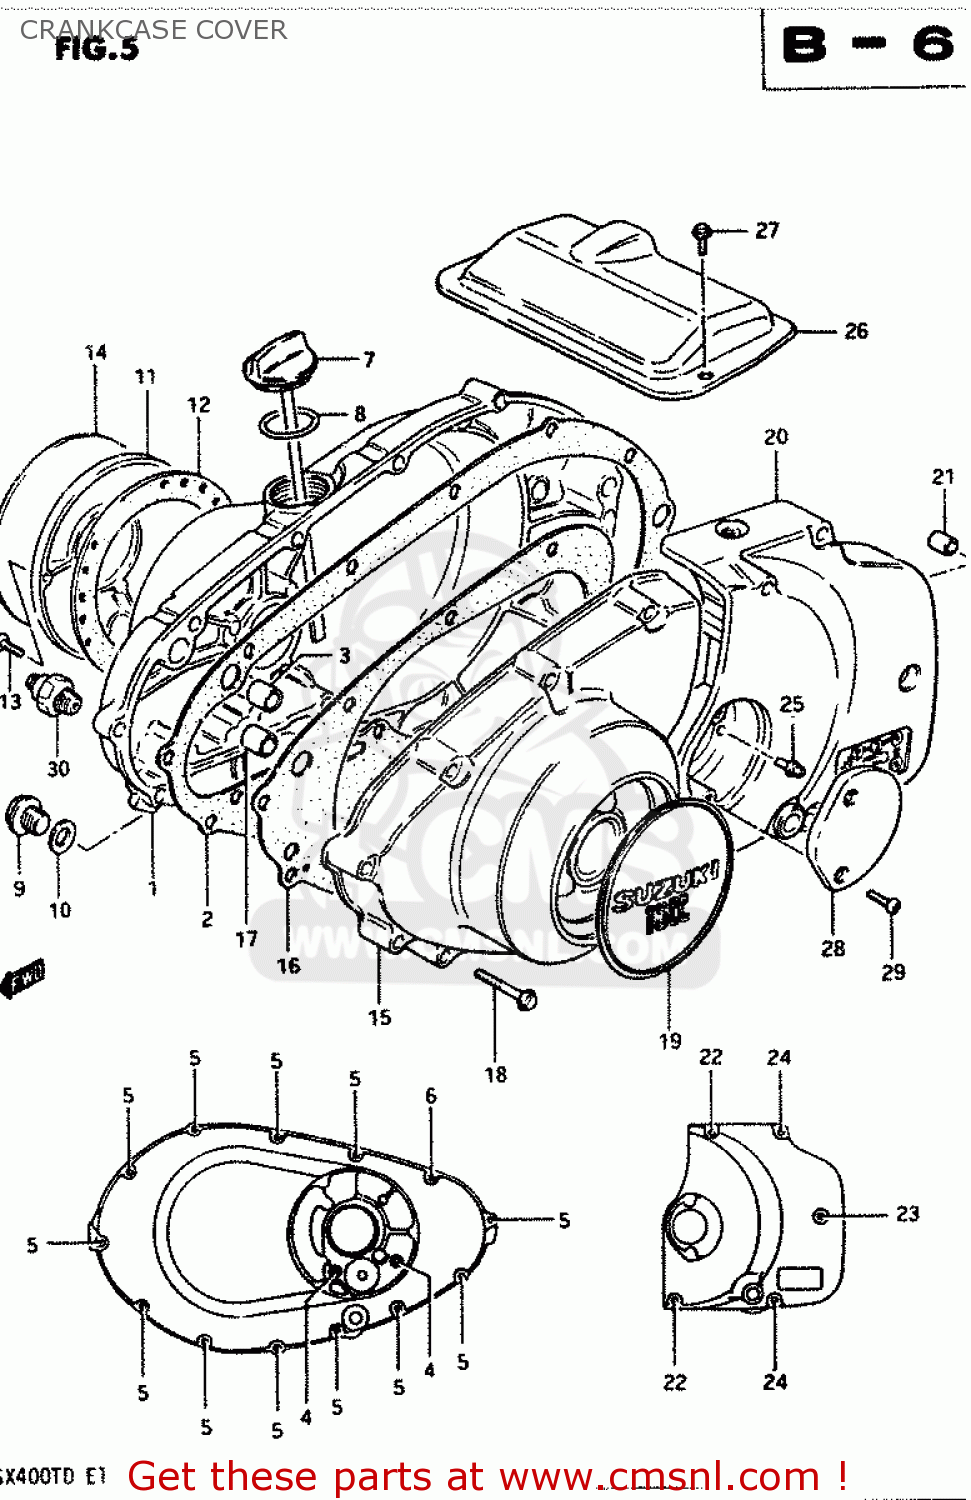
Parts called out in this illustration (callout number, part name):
1	COVER,CLUTCH
2	GASKET,CLUTCH COVER (MCA)
3	PIN
4	BOLT (6X55)
5	BOLT (6X35)
6	BOLT
7	GAUGE,OIL LEVEL
8	O-RING
9	PLUG (14X12)
10	GASKET(14X19.2X2) (NAS)
11	COVER,CONTACT BREAKER
12	GASKET,CONTACT BREAKER COVER (NAS)
13	BOLT 5X16
14	EMBLEM
15	COVER,MAGNETO
16	GASKET,MAGNETO COVER (MCA)
17	PIN
18	BOLT (6X35)
19	EMBLEM
20	COVER,ENGINE SPROCKET
21	PIN
22	BOLT (6X65)
23	BOLT (6X50)
24	BOLT (6X40)
25	NIPPLE
26	COVER,STARTER MOTOR
27	BOLT
28	CAP,CLUTCH RELEASE ADJUST
29	SCREW 5X12
30	SWITCH ASSEMBLY
